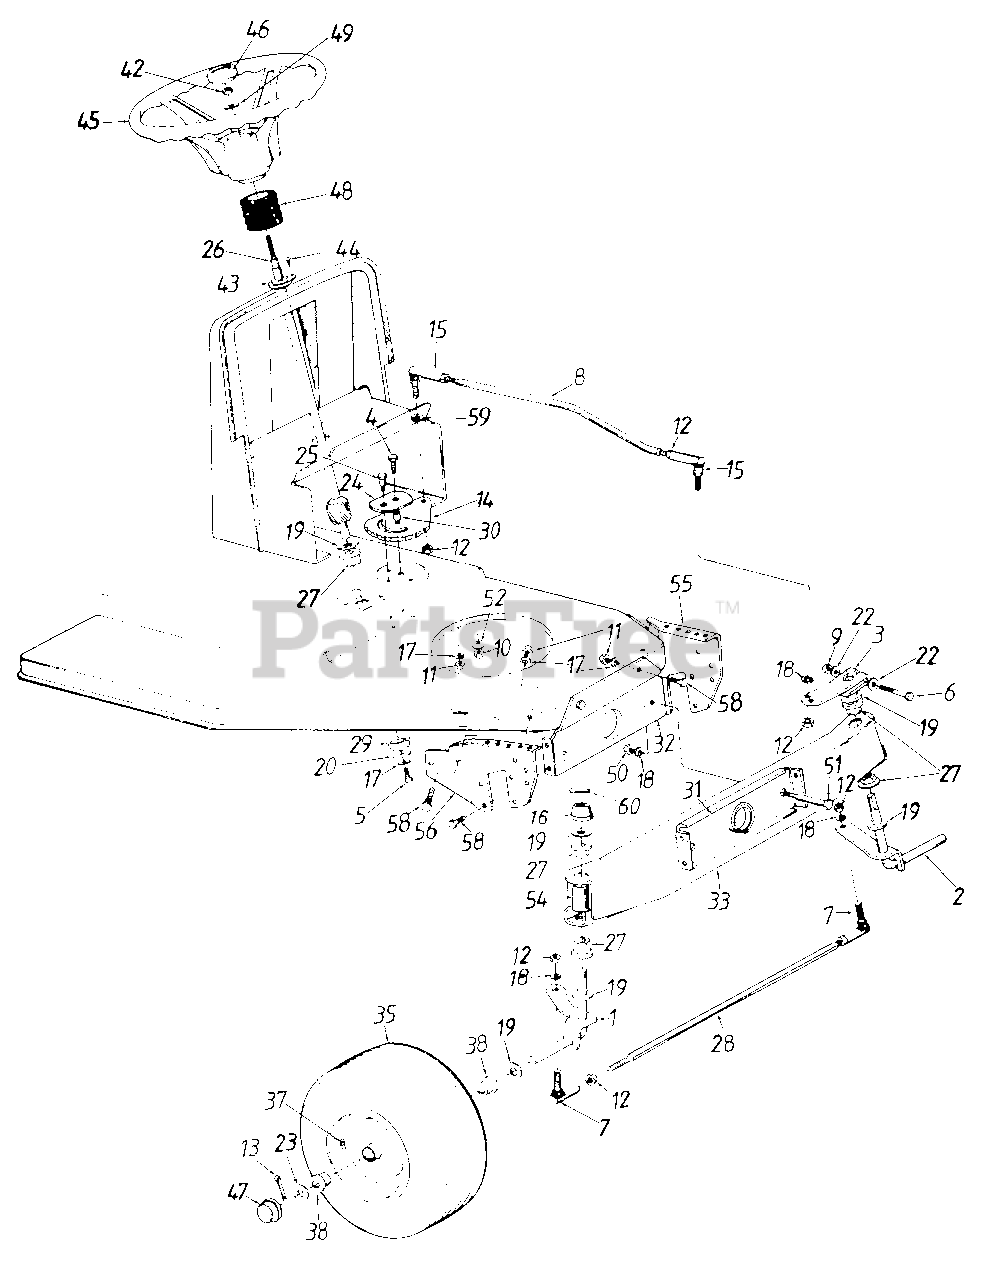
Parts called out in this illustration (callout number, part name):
1	Front Axle Ass'y.-R.H.
2	Front Axle Ass'y.-L.H.
3	Steering Arm
4	Hex Bolt 3/8-24 x 1 Lg.*
5	Hex Bolt 5/16-18 x .62"
6	Hex Bolt 5/16-24 x 2" Lg.*
7	Ball Joint 3/8-24 Thd.
8	Steering Drag Link
9	Hex L-Nut 5/16-24 Thd.
10	Hex Nut 3/8-24 Thd.
11	Hex Nut 5/16-18 Thd.*
12	Hex Jam Nut, 3/8-24 Thd.
13	Cotter Pin 1/8 Dia.
14	Steering Gear Segment
15	Drag Link Ball Joint 3/8-24 Thd.
16	Push Cap
17	L-Wash. 5/16" I.D.*
18	L-Wash. 3/8" I.D.*
19	Fl-Wash. .64" I.D. x 1.24"
20	Fl-Wash. .340" I.D. x 1.125"
22	Spr. Wash. .32" I.D. x .62"
23	Fl-Wash. .635" I.D. x 1.585"
24	Retainer Plate
25	Shld. Bolt .437" Dia. x .350"
26	Steering Shaft
27	Hex Flange Brg. .634 Dia.
28	Tie Rod 20" Lg.
29	Spacer.985" I.D.
30	Spacer.380" I.D.
37	Air Valve
38	Bronze Bearing .63" I.D.
42	Hex L-Nut 5/16-24 Thd.
43	Steering Column Brg.
44	Cr-Sunk Scr. #10 x 5/8" Lg.
45	Steering Wheel
46	Steering Wheel Cap
47	Hub Cap
48	Bellow Steering Column
49	Bell-Wash. .345" I.D. x .88"
50	Hex Nut 3/8-16 Thd.
51	Shld. Bolt 1/2" Dia. x 2.04"
52	Bell-Wash. .39" x 1.38" O.D.
54	Plastic Tube
55	Pivot Bar Side Plate-L.H.
56	Pivot Bar Side Plate-R.H.
58	Hex Wash. Tap Scr. 5/16-18 x .62" Lg.
59	L-Wash. 3/8" I.D. (H.D.)
60	Roll Pin
